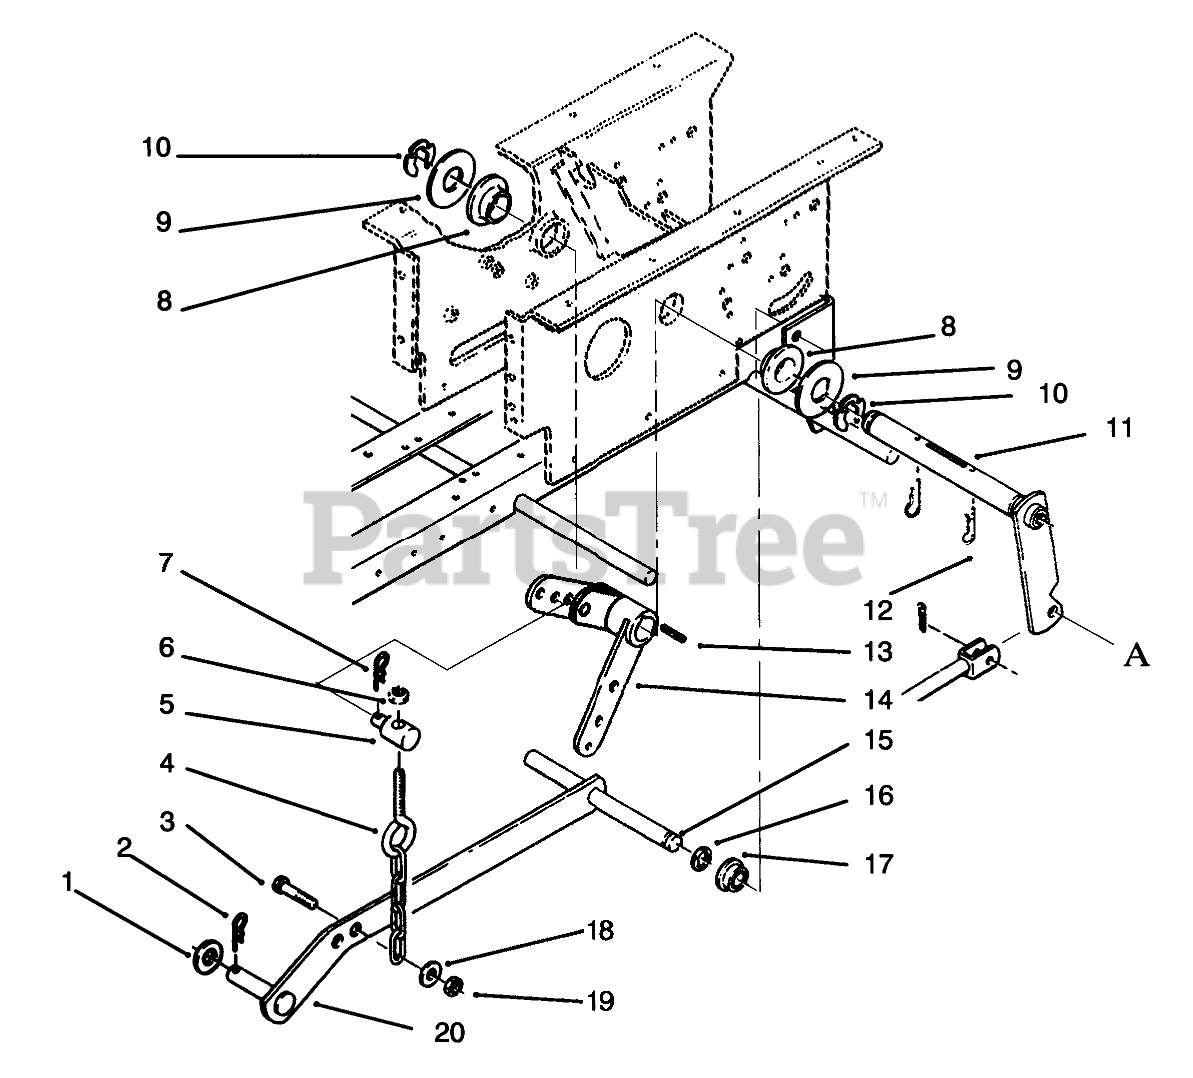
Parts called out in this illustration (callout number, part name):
1	WASHER-FLAT
2	PIN-HAIR
3	SCREW-HH
4	CHAIN-LIFT
5	TRUNNION
6	NUT-LOCK, NI
7	PIN-HAIR
8	BEARING-FLANGE
9	WASHER-FLAT
10	RING-RETAINING
11	WLDMT-LIFT ARM
12	PIN-HAIR
13	KEY-SQUARE
14	WLDMT-LIFT LEVER
15	PIN-PIVOT
16	RING-RETAINING, EXTERNAL
17	BUSHING
18	WASHER-PLAIN
19	NUT-LOCK, NI
20	Bar-Lift
